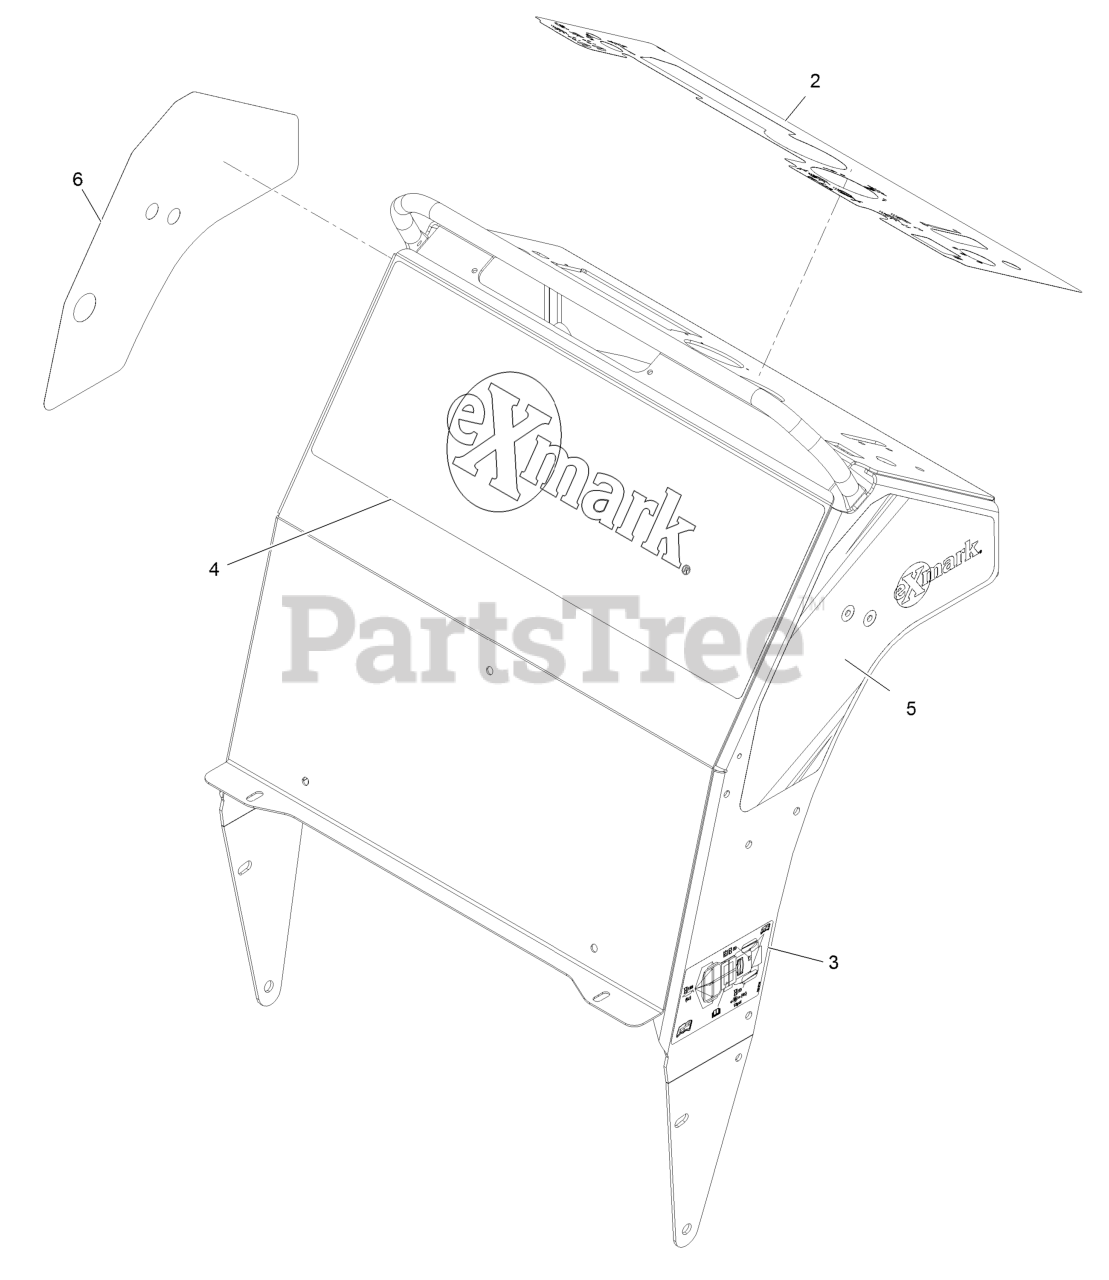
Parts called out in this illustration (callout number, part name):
2	DECAL-CONTROLS
3	DECAL-SERVICE AID
4	DECAL-EXMARK
5	Decal-LH Side Panel Spreader-Sprayer
6	Decal-RH Side Panel Spreader-Sprayer
